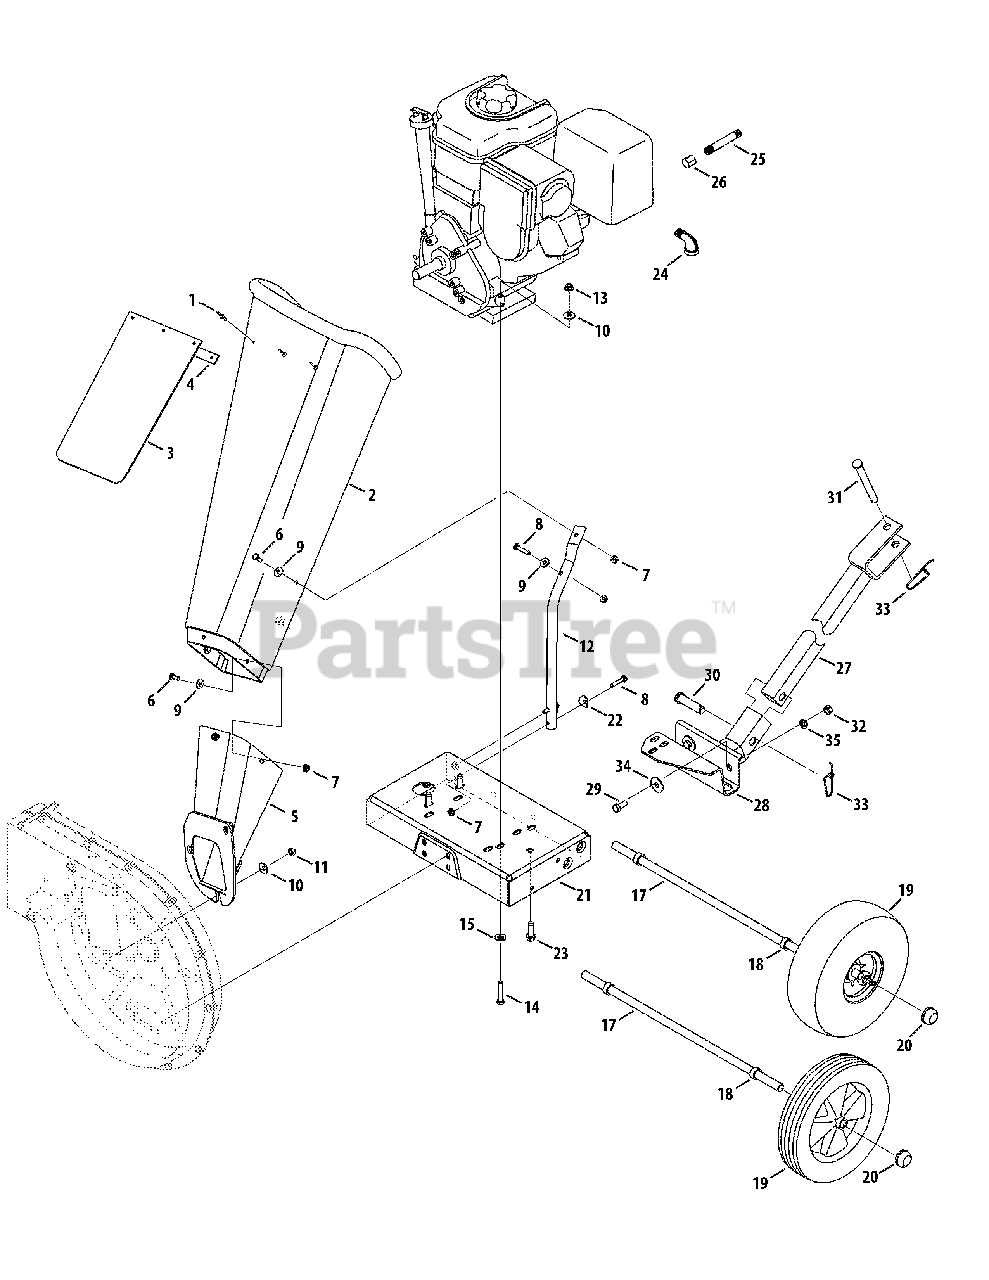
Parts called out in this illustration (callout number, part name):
1	Pop Rivet
2	Chipper Shredder Chute
3	Chute Flap
4	Chute Flap Strip
7	Hex Lock Nut 1/4-20
8	Hex Cap Screw 1/4-20 x 1.25
9	Flat Washer.28 ID x.74 OD
10	Bell Washer.340 ID x.872 OD
11	Hex Nut 5/16-18
13	Hex Lock Nut 5/16-18
14	Hex Cap Screw 5/16-18 x 1.50
14	Hex Cap Screw 5/16-18 x 1.75
15	Bell Washer 5/16 x 1.0
17	Axle Assembly
18	Spacer
19	Wheel Comp., 10.0 x 2.5 Plastic
19	Wheel Complete, 10.0 x 4.0 Gray
20	Push Cap
22	Washer,.320 ID x.93 OD
23	Screw, 3/8-16 x 1.250
24	Elbow Fitting
25	Oil Drain Pipe
26	Oil Drain End Cap
29	Hex Cap Screw, 3/8-16 x.88
30	Clevis Pin,.625 x 2.4
31	Clevis Pin,.50 x 4.62
32	Flange Lock Nut, 3/8-16
33	Spring Pin
34	Flat Washer,.411 x 1.25 x 1.0
35	Lock Washer, 3/8
